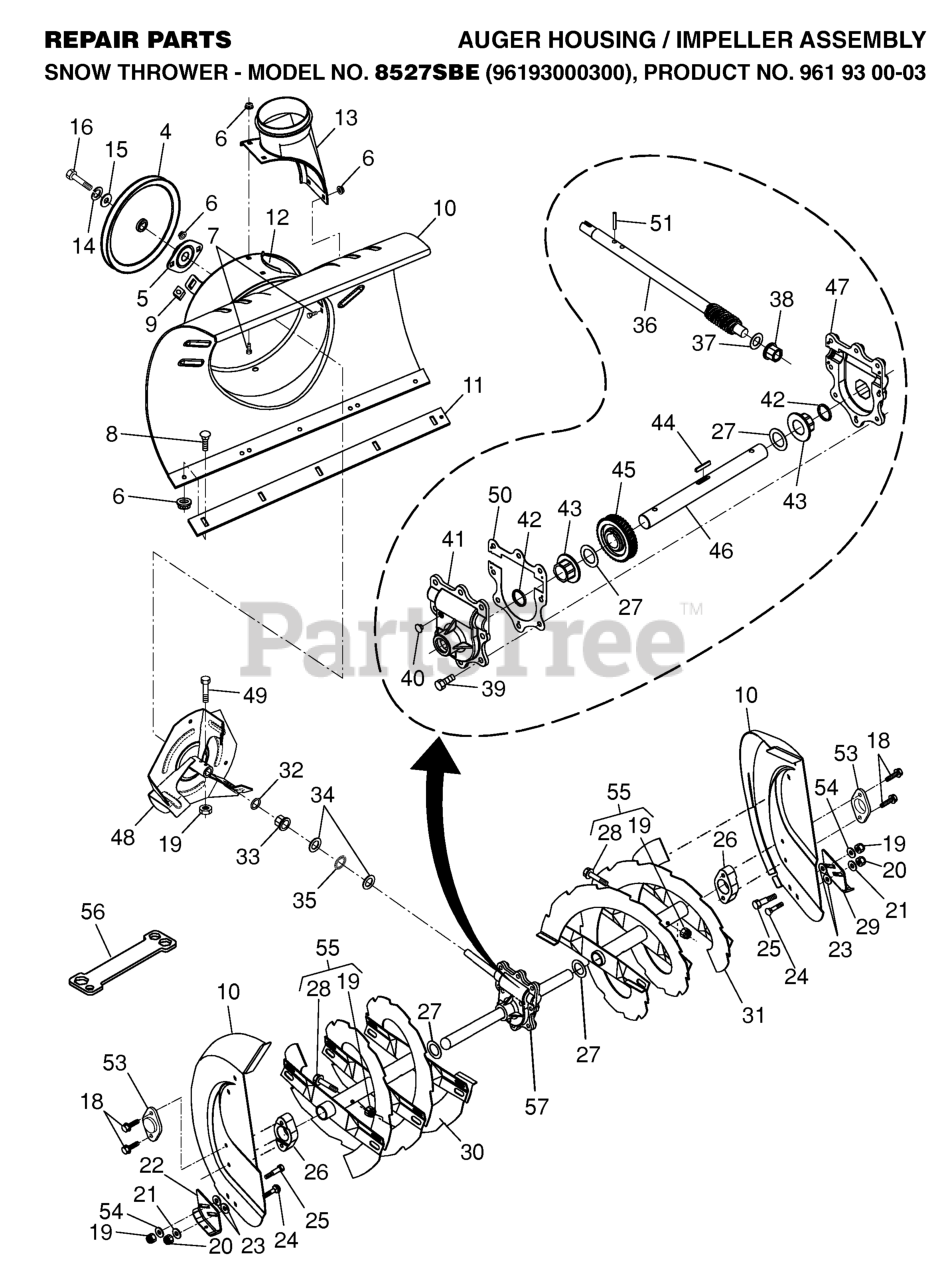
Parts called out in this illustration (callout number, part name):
4	PULLEY, IMPELLER
5	BEARING FLANGE
6	NUT.FLANGE.5/16
7	BOLT.CARRIAGE.5/16-18X
8	BOLT
9	NUT, CAGE 3/8-16
10	KIT.AUGER.HOUSING.404929X668
11	BAR, SCRAPER
12	BRACKET, CORNER DISCHARGE
13	BASE DISCHARGE CHUTE
14	WASHER, FLAT
15	WASHER.LOCK.HVY.HLCL.SPR.5/16
16	Screw, Hex Head 5/16-18 x 3/4
18	SCREW, HEX HD 5/16X1
19	LOCKNUT.NYLOC.1/4-20
20	NUT.71038.31-18.HEX.NYLOCK
21	WASHER.20X8.5
22	SKID PLATE RH
23	WASHER, NYLON FRICTION
24	BOLT
25	SHOULDER BOLT
26	BEARING RETAINER, PLASTIC
27	WASHER TRUST 1"
28	BOLT.SHOULDER.SHEAR.1/4-20.
29	SKID PLATE LH
30	AUGR.ASM.27".RH.PNT
31	AUGR.ASM.27".LH.PNT
33	BUSHING FLANGE 3/4
34	WASHER, THRUST 3/4
35	BEARING TRUST 3/4 NTA-1220
36	SHAFT, IMPELLER
37	WASHER, THRUST 5/8
38	BUSHING.FLANGE.(.625X.75)
39	SELF-TAPPING SCREW 5/16-18X3/4
40	PLUG.AUGER.GEAR.BOX.SNOW
41	HOUSING.GEARBOX.RH.SNOW
43	BUSHING FLANGE 1"
44	KEY, SQUARE 1/4 X .875
45	WORM GEAR
46	SHAFT, AUGER
47	LH GEARBOX HOUSING
48	IMPELLER ASSY
49	SCREW.HEX.HD1/4-20X
50	GASKET.AUGER.GEARBOX
51	PIN, ROLL 3/16 X 1-1/8
53	BEARING.BALL.AUGER.SHAFT
54	WASHER
55	KIT, BOLT, SHEAR
56	RP WRENCH, SNOWTHROWER
57	GEARBOX ASSY.
